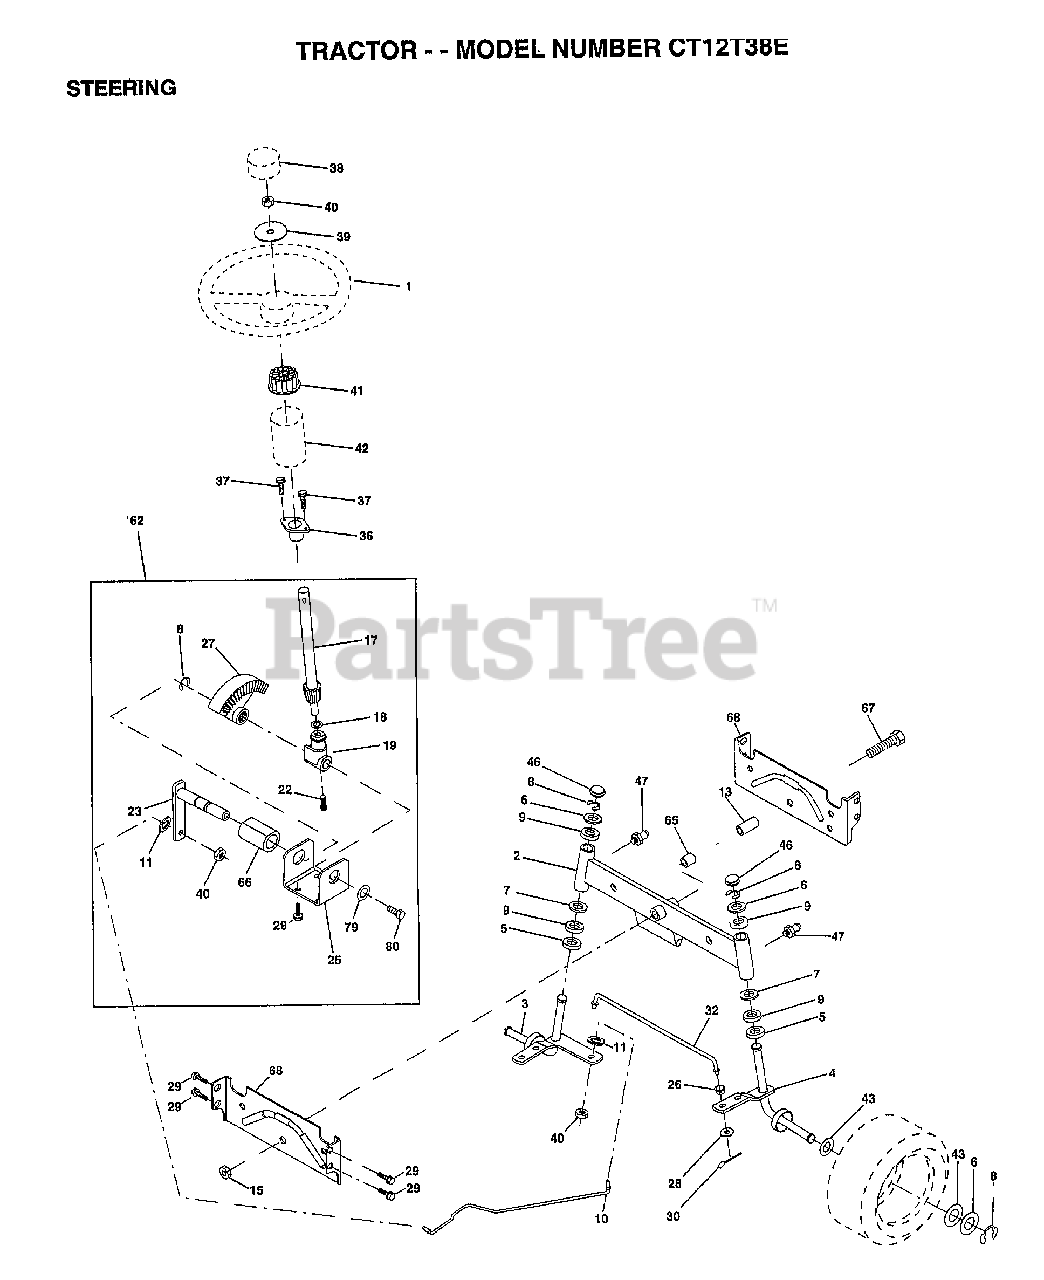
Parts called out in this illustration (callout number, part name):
2	AXLE ASM
3	SPINDLE.ASM.LH
4	"SPINDLE ASM,RH"
5	WASHER .T
6	WASHER
7	WASHER
8	RING
9	COL. SRTG. BEAR.
10	DRAGLINK-STAMPED
11	LOCKWASHER
13	BEARING AXLE
15	"NUT-LOC,FLANGE LT"
17	SHAFT ASSM STEERN
18	THRUST WASHER
19	SUPPORT.SHAFT.STEER
22	SCREW.HX.WSH.HD
23	SHAFT.ASM.PITMAN
25	BRKT-STEERING
26	BUSHING.DRAGLINK
27	GEAR SECTOR
28	WASHER
29	SCREW
30	COTTER PIN
32	TIE ROD
36	BUSHING.STEERING
37	"SCREW-TT,10-32 FL"
38	ST WHL INSERT CAP
39	WASHER T
40	GRIPCO NUT
41	ADAPTER-WHEEL LT
42	"TUBE, STR SHAFT"
43	WASHER
46	CAP
47	ZERK M
62	KIT.STEER.ASM
65	SPACER AXLE
66	"BEARING-ARM,PITMA"
67	BOLT
68	BRACE AXLE
79	WASHER
80	BOLT.HX.NYLON3/8-16X3/
